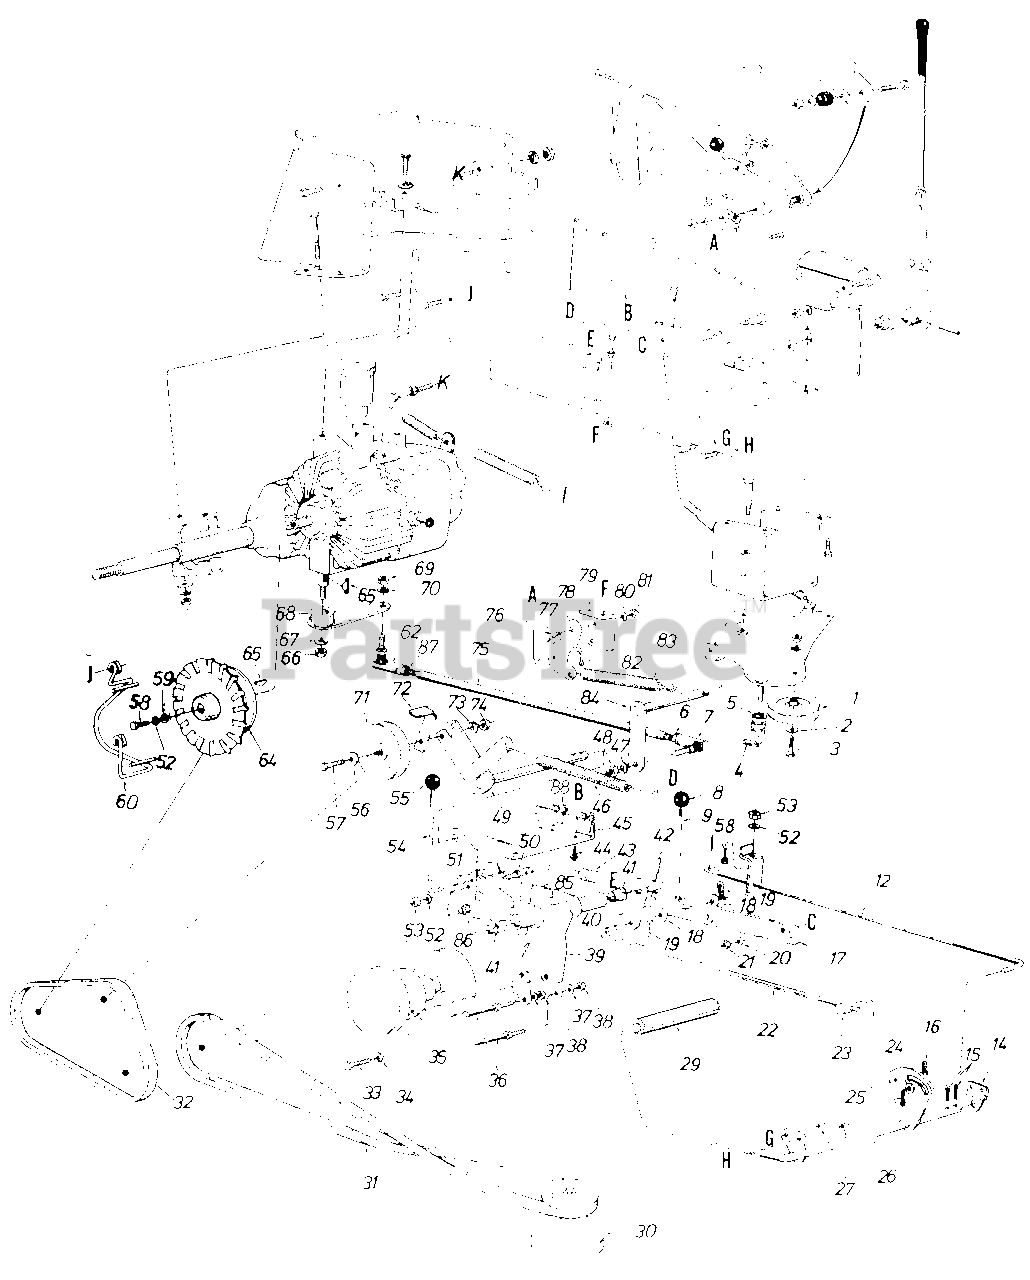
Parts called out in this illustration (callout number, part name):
1	4" Dia. "V"-Idler Pulley
2	Fl-Wash. 3/8" I.D.
3	Hex Bolt 3/8-16 x 1.25" Lg.
4	Intern. Cotter Pin 5/16" Dia.
5	Spacer
6	Hex Jam L-Nut 3/8-24 Thd.
7	Ball Joint Ass'y. 3/8-24 Thd.
8	Ball Knob
9	Parking Brake Link
12	Brake Rod
14	Clutch Rod Brg. Brkt.
15	Cotter Pin 1/8" Dia. x 1.00" Lg.
16	Halrpin Cotter 1/2" Dia.
17	Parking Brake Cam
18	Fl-Wash. .406 I.D. x 1.00" O.D. x .030
19	Hairpin Cotter 1/2" Dia.
20	L-Wash. 5/16" I.D.
21	Hex Nut 5/16-18 Thd.
22	Brake Cam Rod
23	Pivot Bushing
24	Fl-Wash. .401" I.D. x .749" O.D. x .057" Thk.
25	Cotter Pin 3132" Dia. x .75" Lg.
26	Clutch Brake Pedal Ass'y.
27	Hex L-Nut 3/8-16 Thd.
29	Foot Pad
30	Two-Step Engine Pulley 4.75" and 5.56"
31	"V"-Belt 1/2 " X 59" Lg.
32	"V"-Belt 1/2" X 37" Lg.
33	Hex Sems Bolt 5/16-18 x .75" Lg.
34	L-Wash. 5/16" I.D.
35	Jack Shaft Ass'y.
36	Stud 3/8-16 x 3.62" Lg.
37	L-Wash. 3/8" I.D.
38	Hex Nut 3/8-16 Thd.
39	Jack Shaft Mtg. Brkt. Ass'y.
40	Clutch Idler Horn Ass'y.
41	Nyliner 5/8" I.D. x .88" Lg.
42	Spring Pin Spiral 1/4" Dia. x 1.5" Lg.
43	Ext. Spring
44	Hex Wash. Hd. Self-Tap Scr. 1/4-20 X .50" Lg.
45	Idler Mtg. Brkt.
46	Ext. Spring
47	L-Wash. 3/8" I.D.
48	Hex Nut 3/8-24 Thd.
49	Clutch Brkt. Ass'y.
50	Hex Bolt 1/4-20 x .50" Lg.
51	Internal Cotter Pin 5/16" Dia. Rod
52	L-Wash. 1/4" I.D.
53	Hex Nut 1/4-20 Thd.
54	Relief Valve Lockout Rod
55	Ball Knob
56	Fl-Wash. 3/8" I.D.
57	Hex Bolt 3/8-16 x 1.25" Lg.
58	Hex Bolt 1/4-20 x .62" Lg.
59	Fl-Washer
60	Belt Guard Ass'y.
62	Ball Joint Ass'y. 3/8-24 L.H. Thd.
64	Transaxle Pulley w/Fan
65	Hi-Pro Key 1/8" x 1/2" Dia.
66	Hex Nut 3/8-16 Thd.
67	L-Wash. 3/8" I.D.
68	Pintle Arm Ass'y.
69	Hex Nut 3/8-24 Thd.
70	L-Wash. 3/8" I.D.
71	4" "V"-Idler Pulley
74	Hex Nut 3/8-16 Thd.
75	Speed Control Rod
76	Deck Control Rod
77	Shld. Scr. .437" Dia. x .162" Lg. (5/16-18)
78	Deck Control Pivot Brkt.
79	Parking Brake Cam Mtg. Brkt.
80	L-Wash. 5/16" I.D.
81	Hex Nut 5/16-18 Thd.
82	Internal Cotter Pin 5/16" Rod
83	Extension Spring
84	Speed Control Shaft Ass'y.
85	Relief Valve Cam L.H.
86	Relief Valve Cam R.H.
87	Hex Jam L-Nut 3/8-24 L.H. Thd.
88	Plastic Hose Clamp
